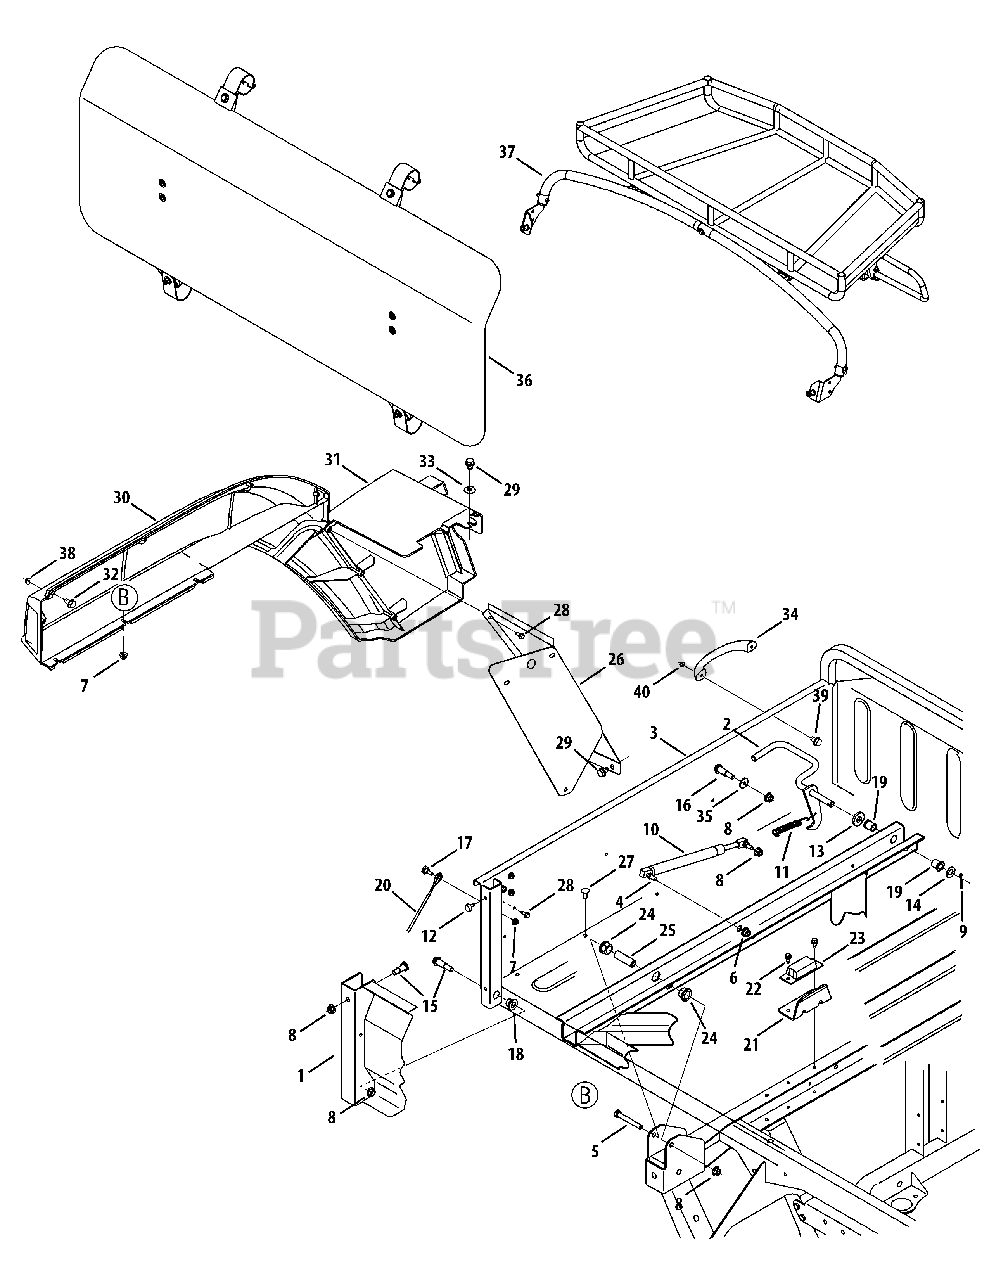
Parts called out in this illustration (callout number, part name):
2	Lvr Asm, bed, latch
4	Stud, ball, 5/16-18
5	Screw, 3/8-16, 2.75, gr5, std
6	Nut, flglk, 5/16-18, grf, nylon
7	Nut, flglk, 1/4-20, grf, nylon
8	Nut, flglk, 3/8-16, grf, nylon
9	Pin, cot, 5/32, 1.25
10	Spr, gas, 6.91 Stroke
11	Spr, extn, .50 Od X 4.35 Lg
12	Bmpr, .62 Dia. x .3
13	Wash, flat, .531 X 1.25 X .181
14	Wash, flat, .510 X 1.00 X .060
15	Scr, shldr, .50 X .685, 3/8-16
16	Scr, shldr, .50x.925, 3/8-16
17	Scr, shldr, .375x.280, 1/4-20
18	Brg, flg, hex, .506 Id X .590 Lg
19	Brg, flg, .503 X .689 X .792
20	Cbl, lanyard
22	Scr, tt, 1/4-20x.625, hxindwsh
23	Bmpr, suspn, extn
24	Brg, hex Flng .629 Id
25	Spcr, .390 Id X.625 Od X2.03 Lg
27	Scr, Crg, 1/4-20, .62, Gr2
28	Scr, #12-16, .50, Hxindwsh
29	Scr, Tt, 5/16-18, 0.500
30	Fdr, Lh Rr
30	Fdr, Lh Rr, Camo
31	Fdr, Lwr Lh Rr
31	Fdr, Lwr Lh Rr, Camo
32	Screw, Mach., 1/4-20 x .500
33	Washer, Bell, .340 x .872 x .060
35	Washer, Flat, .385 x .870 x .092
36	Head Rest
37	Hood Rack
38	Nut, Acorn, 1/4-20
39	Screw, Mach., 1/4-20 x .750
40	Nut, Hexlk., 1/4-20
